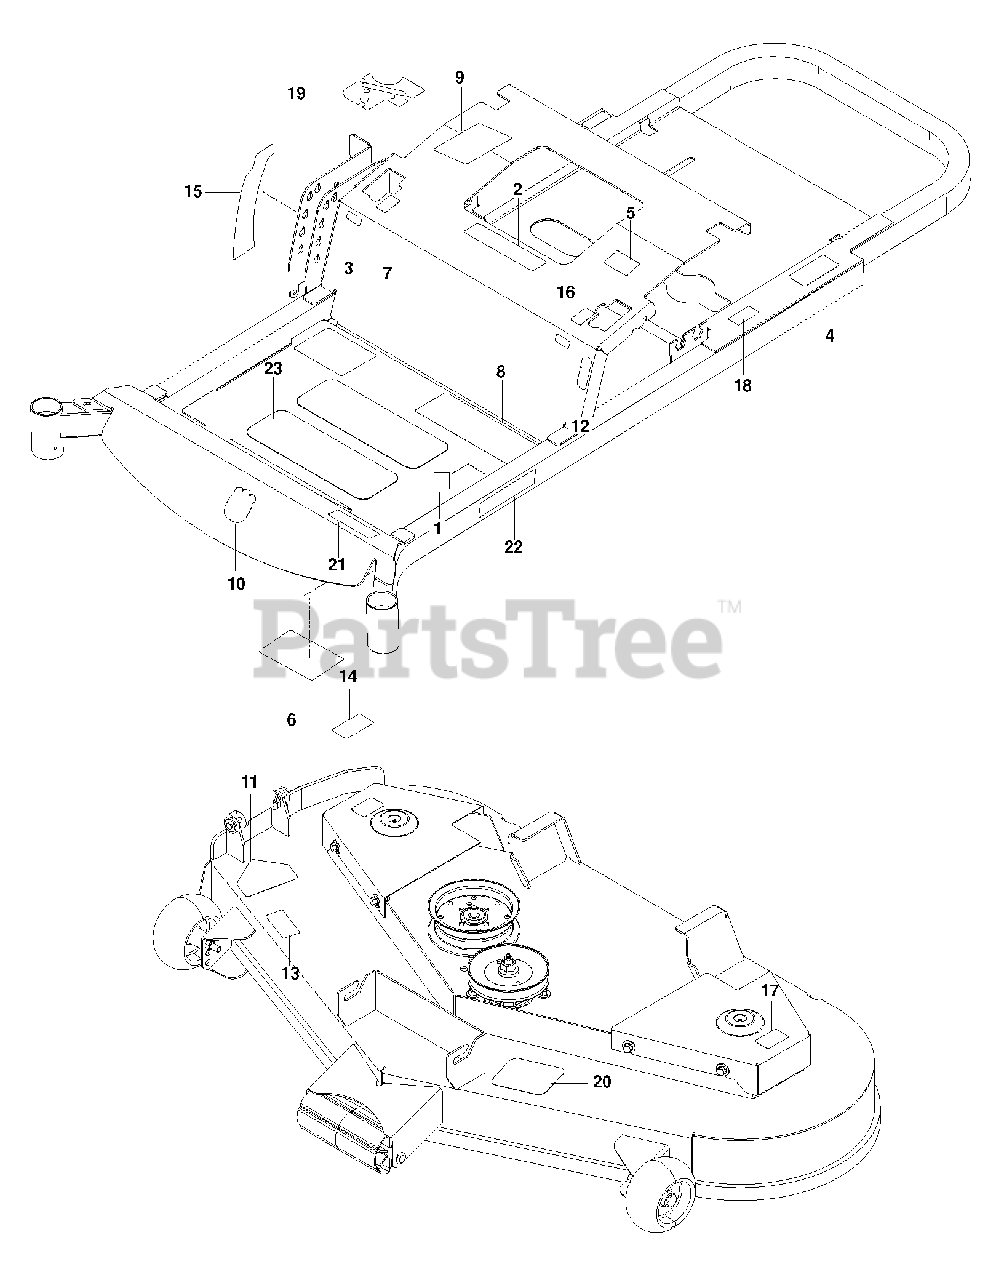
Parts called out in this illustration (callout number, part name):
1	DECAL 80 DBA
2	EURO DECAL-BATTERY WARNIN6
3	DECAL.ZTR.STRTNGINST.REMOTECHK
4	DECAL, DO NOT TOW
5	DECAL, EXITING MOWER
6	DECAL, SERVICE
7	DECAL, MOTION CONTROL
8	DECAL, SAFETY WARNING
9	DECAL, CUSTOMER RESPNSIBILITY
10	DECAL.AUGER.HUSQ.CROWN.SNOW
11	DECAL, CPSC
12	DECAL, PARK BRAKE
13	DECAL, EURO SEVERING
14	DECAL.DECK.6MIL./DEF.SHLD.WARN
15	DECAL, HEIGHT
16	DECAL, F.S.T.
17	DECAL.DECK.6MIL.EURO.NOSTEP
18	DECAL, ECM, AUSTRALIA
19	DECAL.CNTRLPANEL.C/START.RZ
20	DECAL, BELT ROUTING
21	Decal, ZTR RZ4222TF Husqvarna
22	RP.DECAL.BADGE.170MM.TEXTLOGO
23	ANTI-SKID PAD
